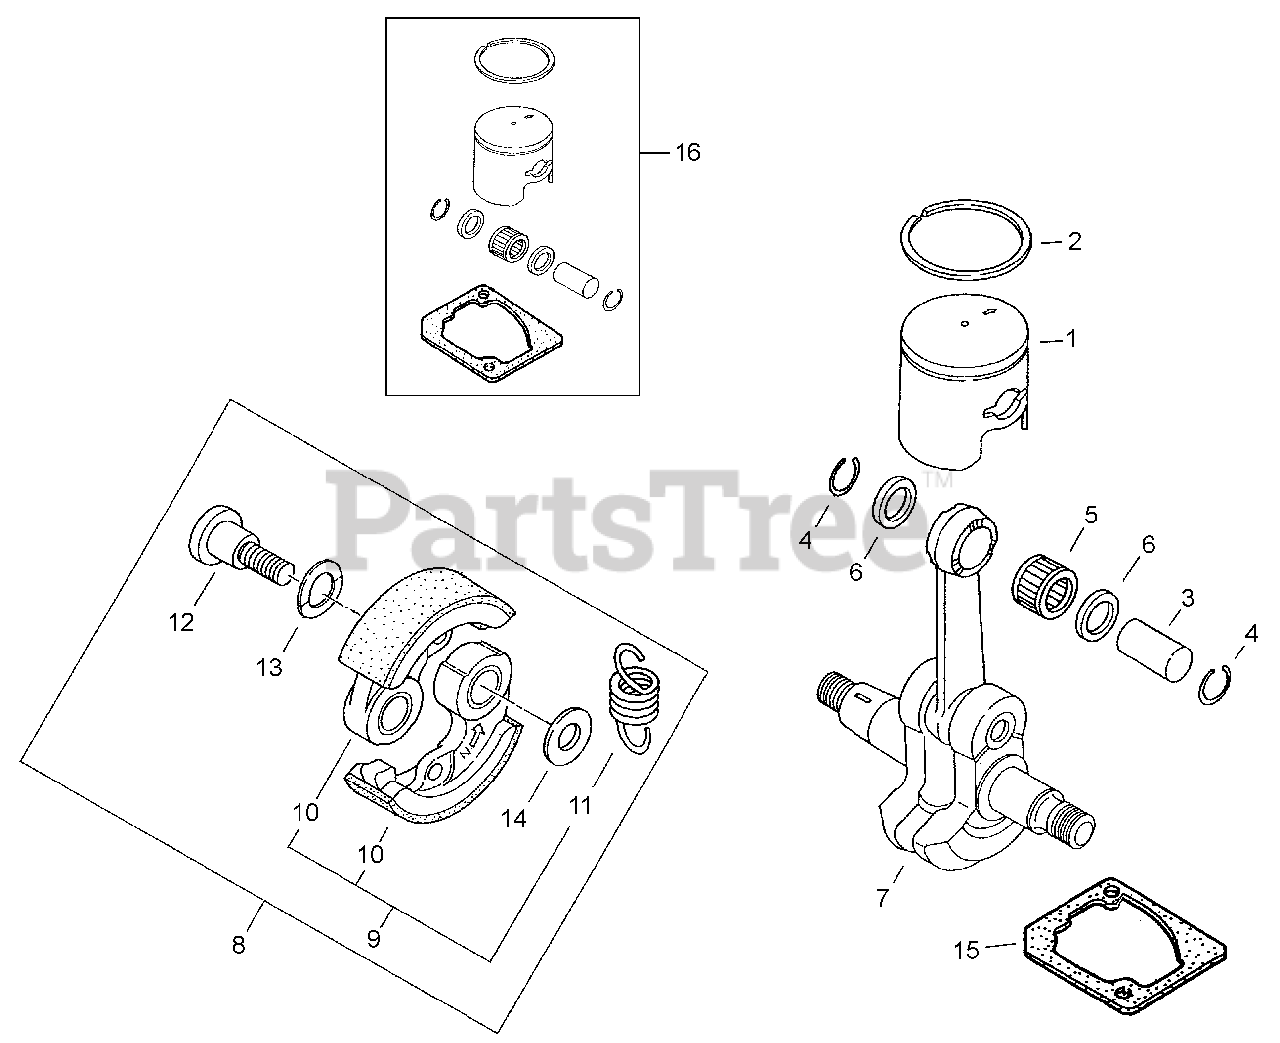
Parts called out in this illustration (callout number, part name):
2	RING, PISTON
3	PIN, PISTON
4	RING, RETAINING
4-1	PISTON
5	BEARING, NEEDLE
6	SPACER, PISTON
7	CRANKSHAFT
8	CLUTCH ASSY
9	CLUTCH SHOE KIT
10	SHOE, CLUTCH
11	SPRING, CLUTCH
12	BOLT, CLUTCH
13	WASHER - SPRING
14	WASHER
15	GASKET, CYLINDER
16	PISTON KIT
